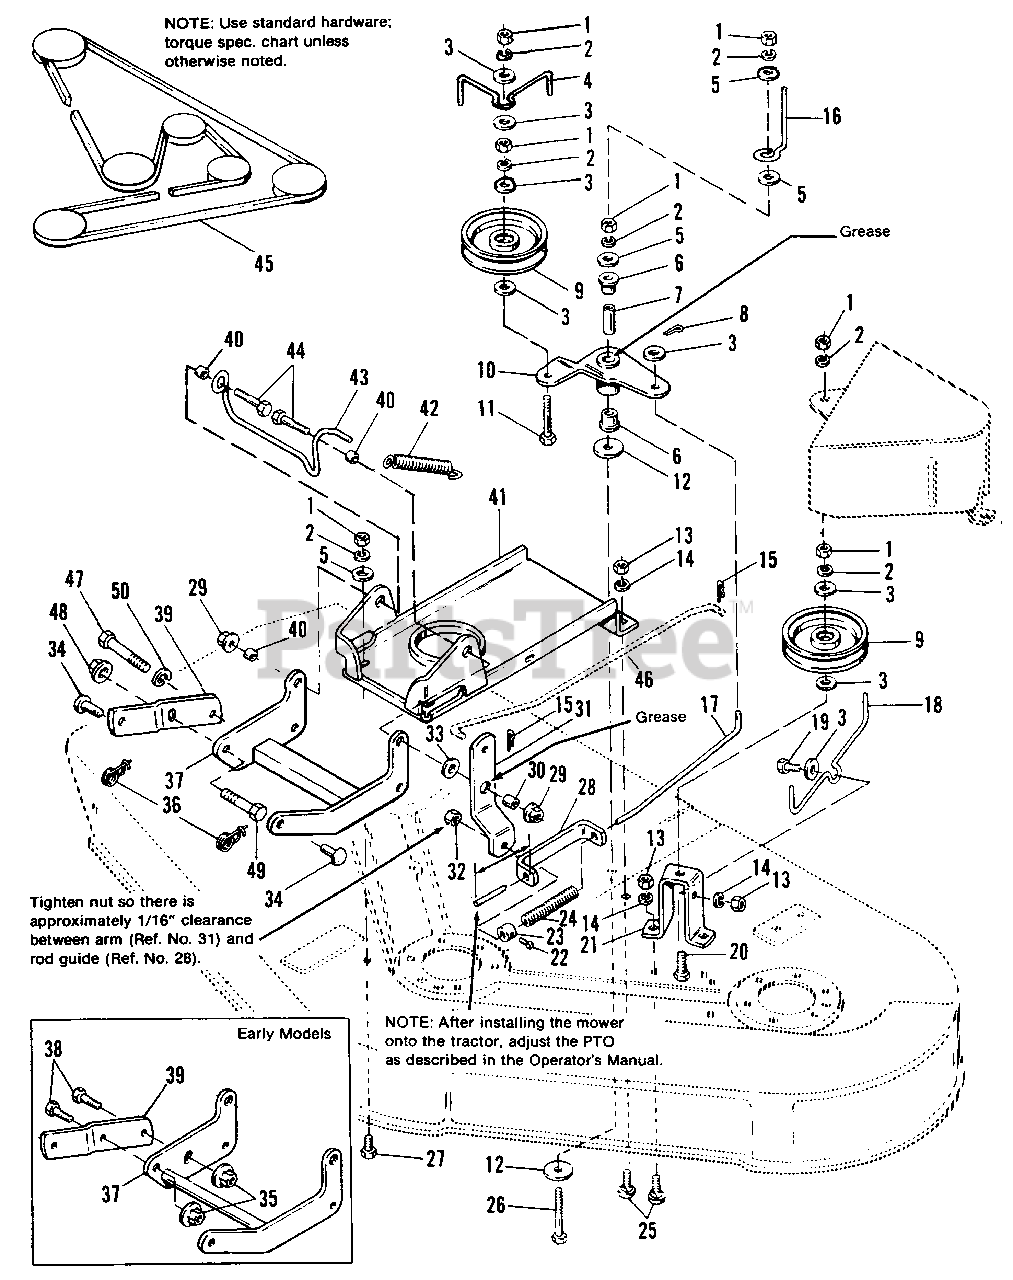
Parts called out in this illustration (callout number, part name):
1	NUT, Hex, 3/8-16
2	LOCKWASHER, 3/8
3	WASHER, Plain, 5/16
4	STOP, Belt
5	WASHER, Plain, 3/8
8	PIN, Cotter, 3/32 x 3/4
9	PULLEY, Idler
10	LEVER ASSY., Clutch
11	CAPSCREW, Hex, 3/8-16 x 2-1/4
12	WASHER, Special
13	NUT, Hex, 5/16-18
14	LOCKWASHER, 5/16
15	PIN, Quick, 1-7/8
17	ROD, Clutch, Mower
19	CAPSCREW, Hex, 5/16-18 x 1
20	CAPSCREW, Hex, 3/8-16 x 2
21	SUPPORT, Idler
22	SETSCREW, Sq. Hd., 1/4-20 x 3/8
23	COLLAR, Set
25	BOLT, Carriage, 5/16-18 x 3/4
26	CAPSCREW, 3/8-16 x 3-1/2
27	CAPSCREW, Hex, 3/8-16 x 3/4
28	GUIDE ASSY., Rod
29	NUT, Hex, Flange, 3/8-16
31	ARM, Pivot
32	LOCKNUT, Hex, 5/16-18
33	WASHER, Plain, 3/8
35	LOCKNUT, Flange, Whiz, 3/8-16
36	PIN, Safety
37	ARM ASSY., Rocker
38	CAPSCREW, Hex, 3/8-16 x 1
39	ARM, Rocker
41	SUPPORT ASSY.
42	SPRING, Tension
44	CAPSCREW, Hex, 3/8-16 x 1-3/4
45	V-BELT, Mower Drive
46	ROD, Clutch, Tractor P.T.O.
47	CAPSCREW, Hex Hd., 7/16-14 x 1-1/2
48	NUT, Hex, Whizlock, 7/16-14
49	CAPSCREW, Hex Hd., 7/16-14 x 1-1/4
50	LOCKWASHER, 7/16
